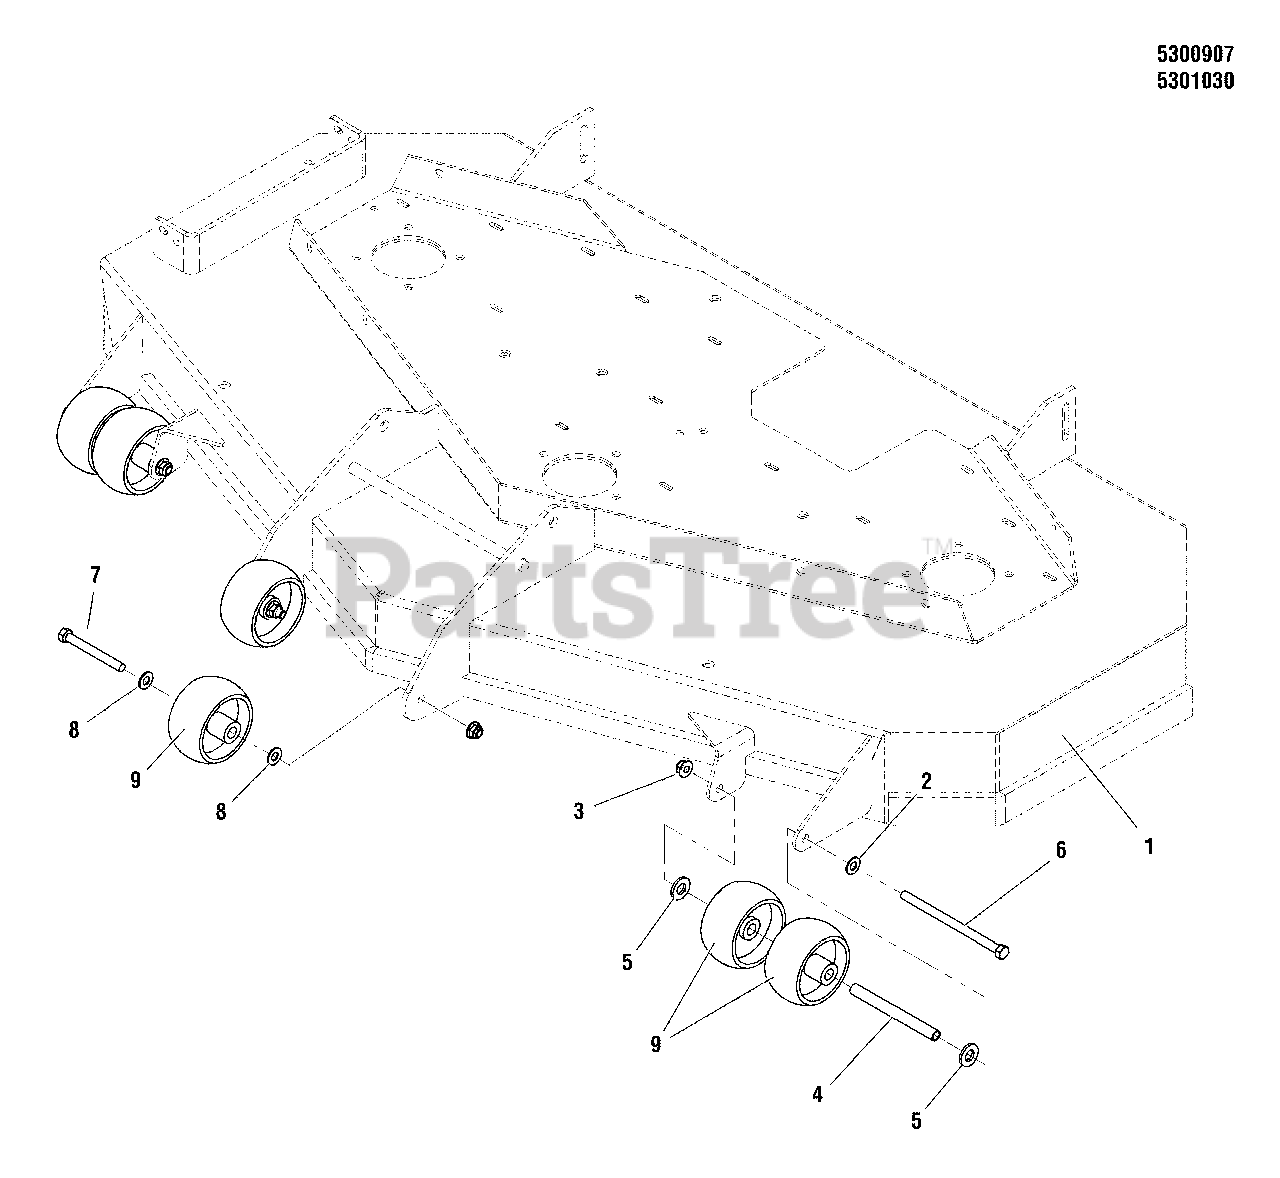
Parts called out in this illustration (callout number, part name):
1	MOWER DECK
2	WASHER, 3/8 SAE
3	NUT, 3/8-16 HEX NYLOCK FLANGE
4	SPACER, .38 X .50 X 5.06
5	WASHER, 1/2 SAE
6	BOLT, 3/8-16 X 6" GD5 CZ
7	BOLT-WHEEL 3/8-16X2.781 .750 THRD YELLOW
8	WASHER,.516IDX.875ODX.06,FLAT,ZC/CL
9	GAUGE WHEEL
